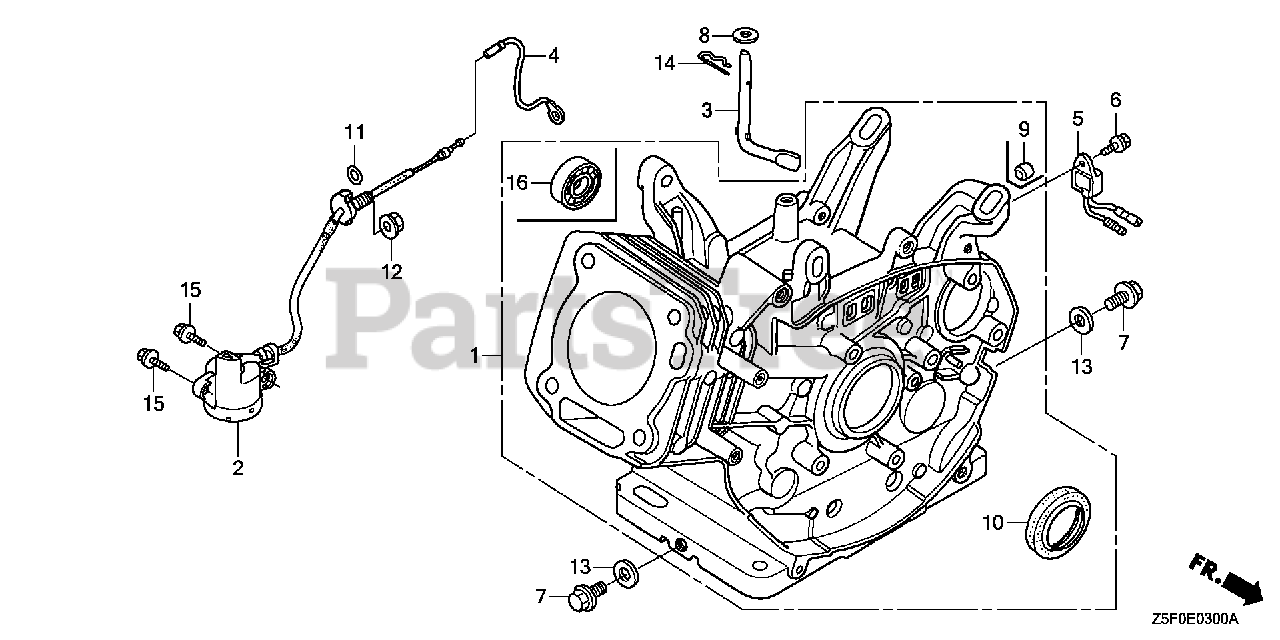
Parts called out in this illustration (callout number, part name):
1	CYLINDER ASSY.
2	SWITCH ASSY., OIL LEVEL
3	SHAFT, GOVERNOR ARM
7	BOLT, DRAIN PLUG
8	WASHER (8.2X17X0.8)
10	OIL SEAL (30X46X8) (NOK ASIA)
11	O-RING (14MM) (ARAI) Use up to Engine SN 2949254.
11	O-RING (14MM) (NOK)
12	NUT, FLANGE (10MM)
13	WASHER, DRAIN PLUG (12MM)
14	PIN, LOCK (10MM)
15	BOLT, FLANGE (6X12) Use up to Engine SN 1543277.
